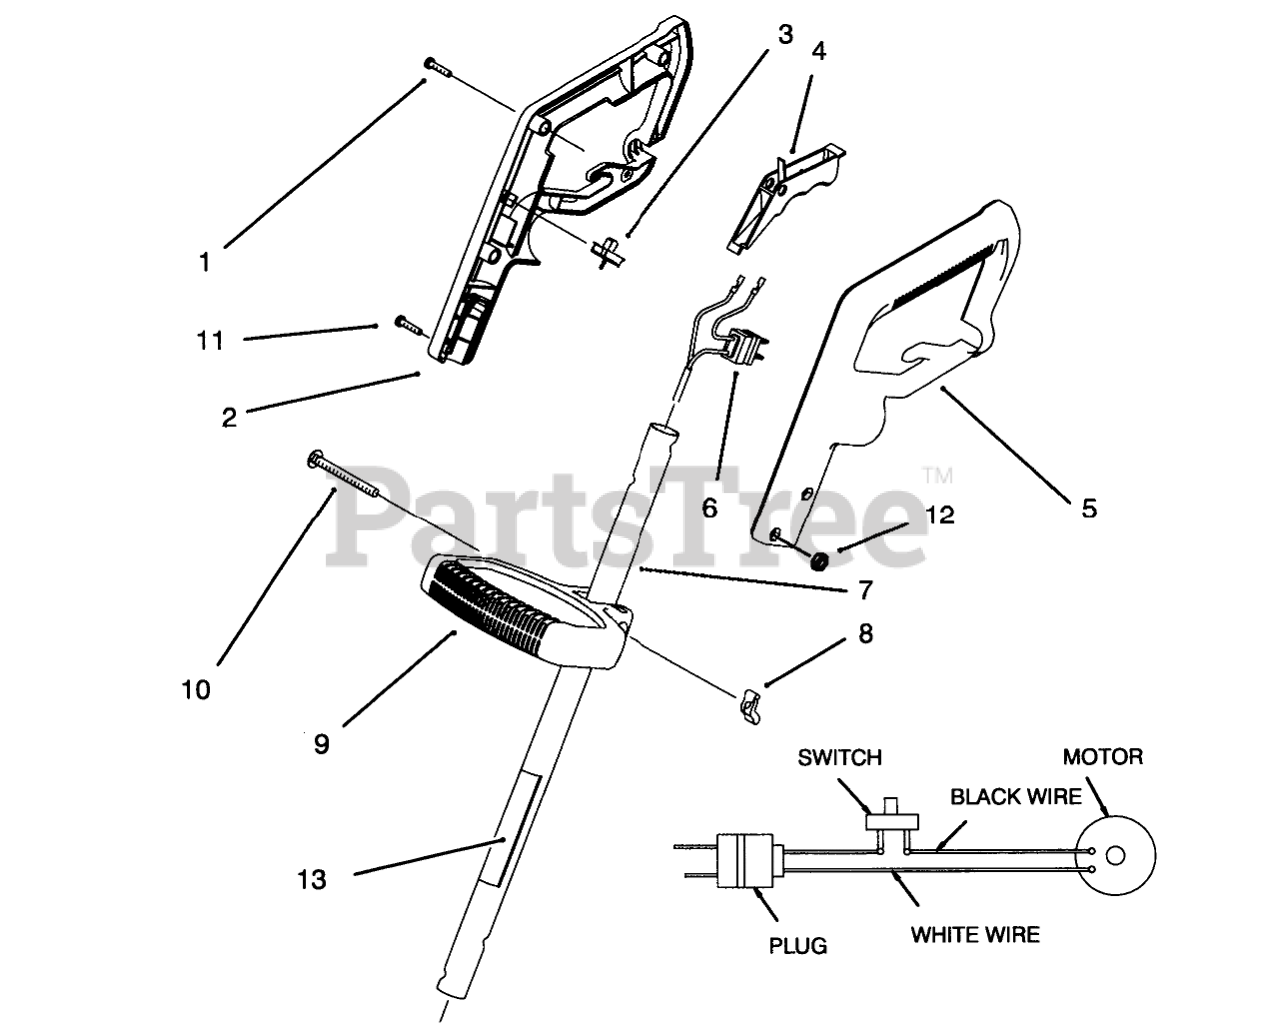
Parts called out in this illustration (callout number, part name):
1	Screw
2	HAND GRIP R.H.
3	SWITCH
4	TRIGGER
5	HAND GRIP L.H.
6	WIRING HARNESS
7	Tube Assembly (Incl. Ref. #13)
8	1/4"-20 STAMP WNG NUT
9	MID HANDLE
10	SCREW-CARR.25-20 X 2.50
11	SCREW-PPH
12	NUT-HEX
13	Decal-Safety
